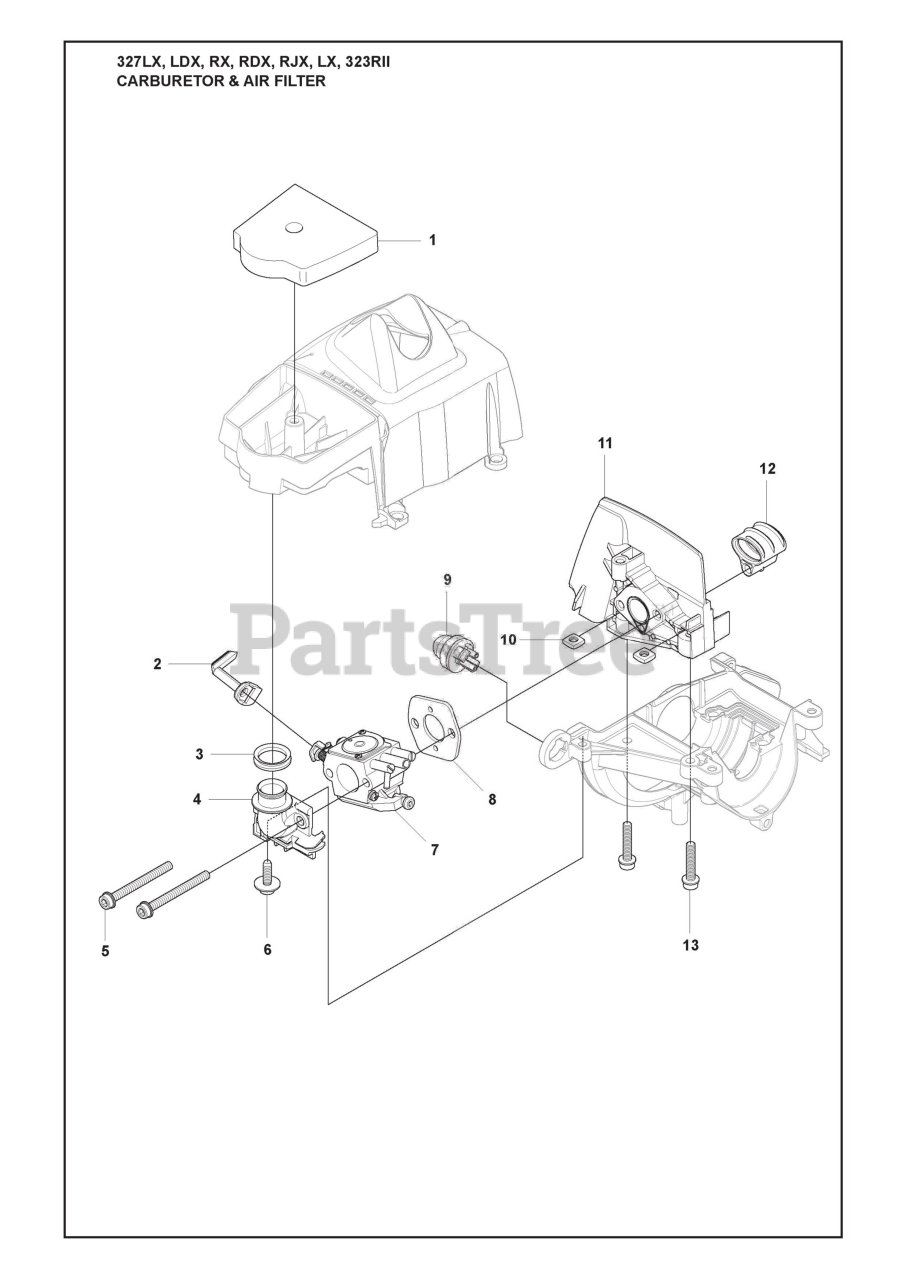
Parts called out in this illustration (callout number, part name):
1	AIR FILTER
2	CHOKE CONTROL
7	CARBURETOR
9	AIR PURGE BUBBLE
